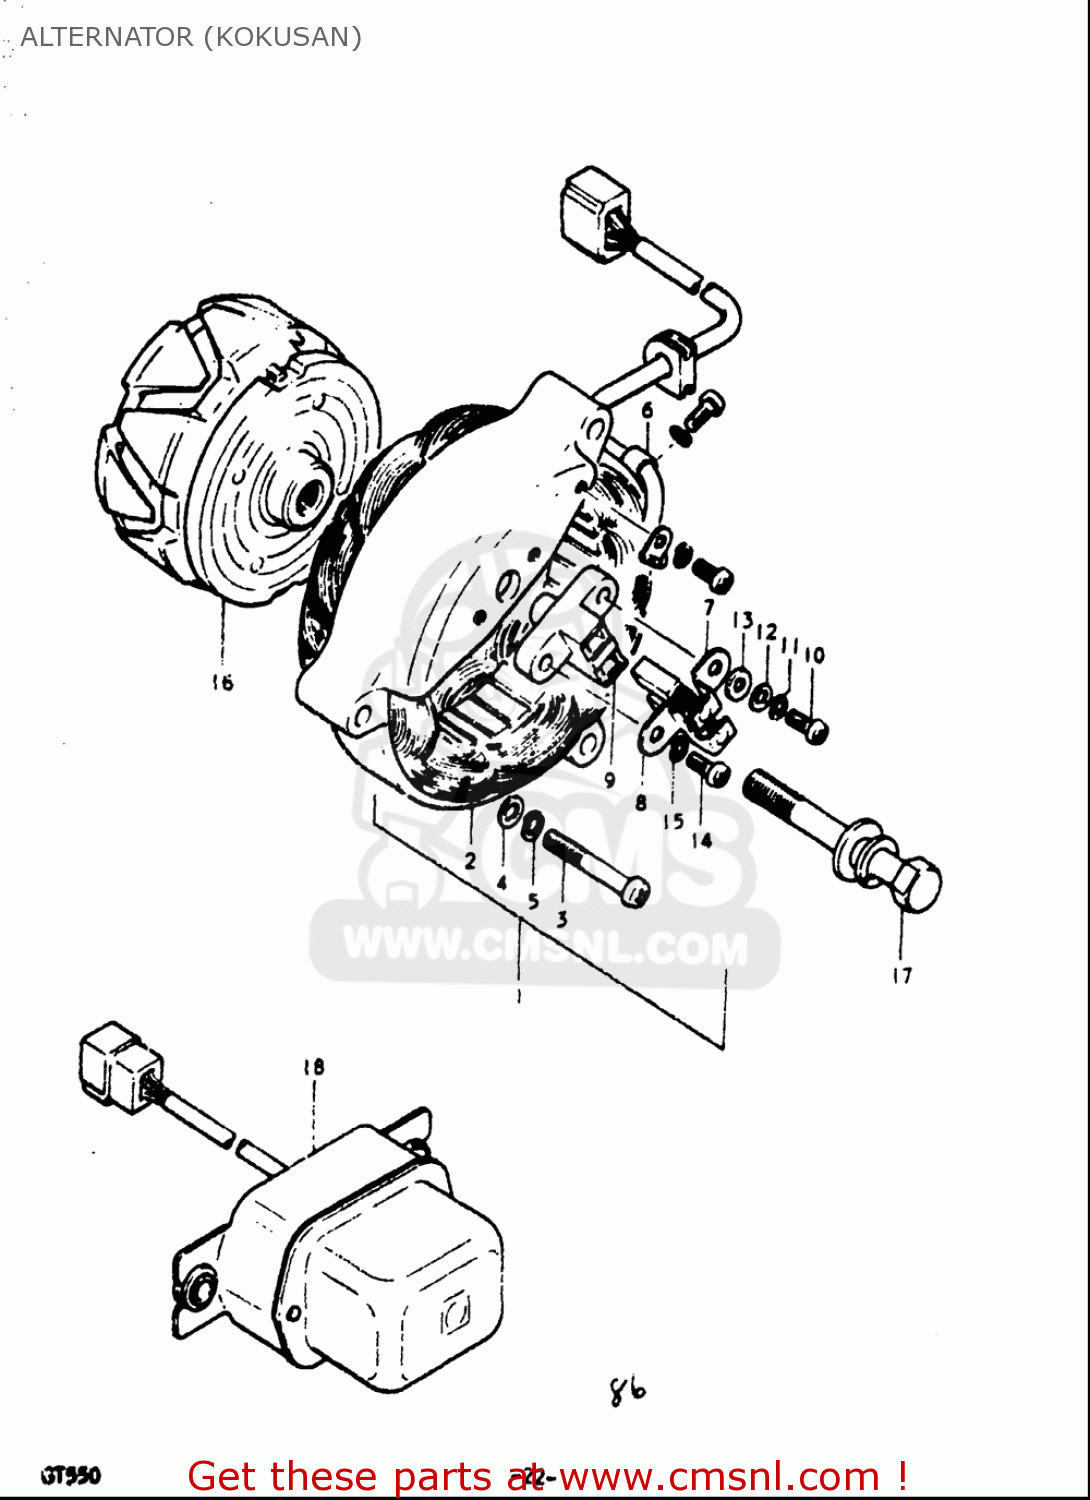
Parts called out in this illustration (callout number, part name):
4	WASHER
5	WASHER,LOCK
7	BRUSH
8	BRUSH
10	SCREW 4X16
11	WASHER,LOCK
12	WASHER
14	SCREW
15	WASHER,LOCK
17	BOLT
